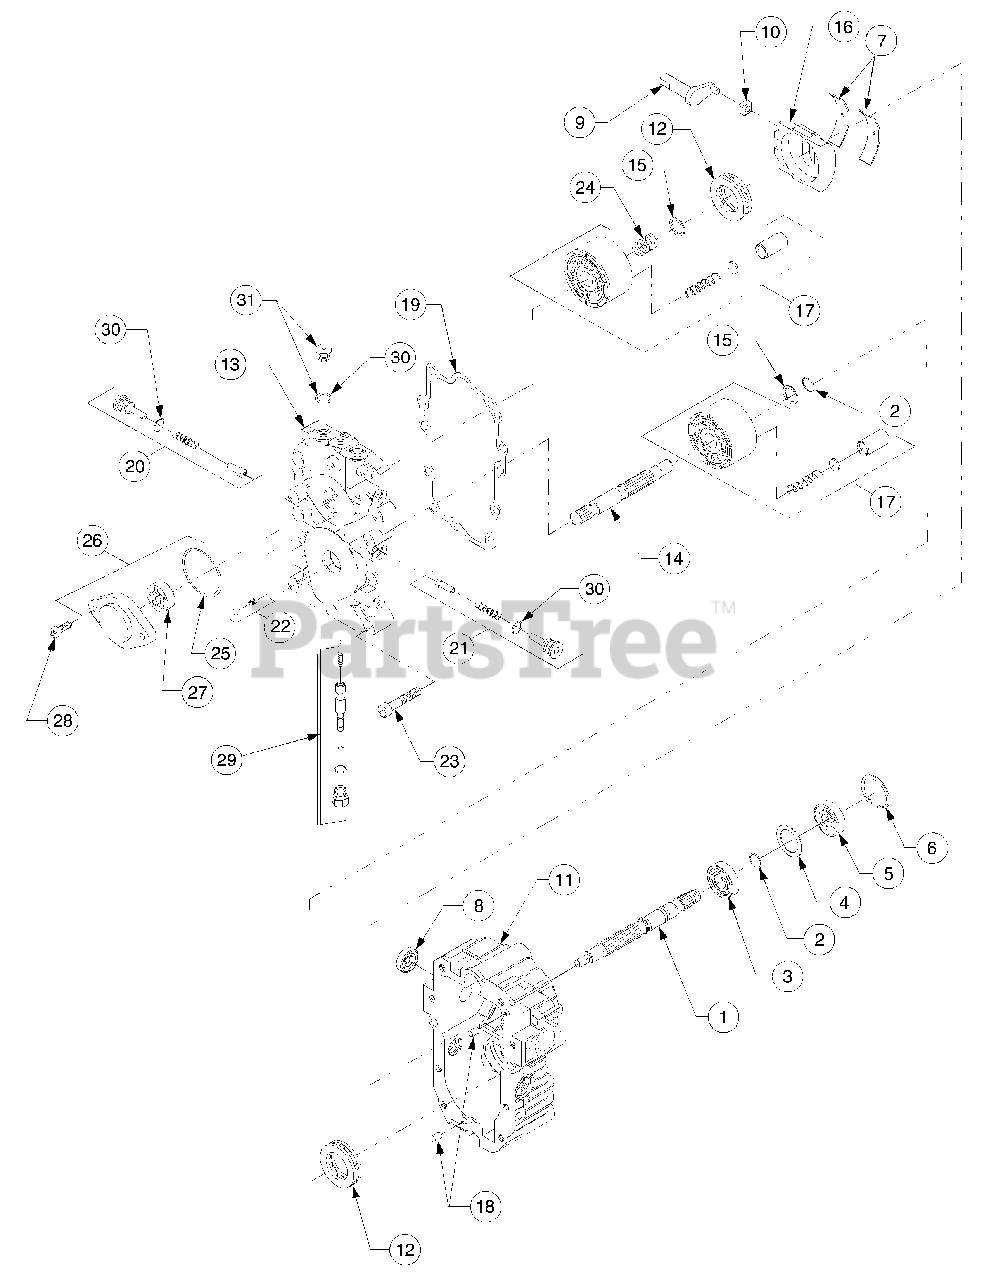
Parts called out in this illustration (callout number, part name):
1	Shaft, Pump (Splined)
2	Ring, Retaining
3	Bearing, Ball
6	Ring, Retaining
7	Bearing, Cradle
9	Arm, Trunnion
10	Guide, Slot
11	Housing Kit
12	Bearing Assembly, Thrust Ball
13	Center Section Kit
14	Shaft, Motor
15	Washer, Block Thrust
16	Swash Plate
17	Block Assembly
19	Gasket, Center Section
20	Kit, Check Valve
21	Kit, Orificed Check Valve
22	Kit, Charge Relief Valve
23	Screw, Socket Hd
24	Spring, Block
26	Kit, Charge Pump
27	Gerotor Assy
28	Screw, Socket Hd
29	Bypass Valve Kit
